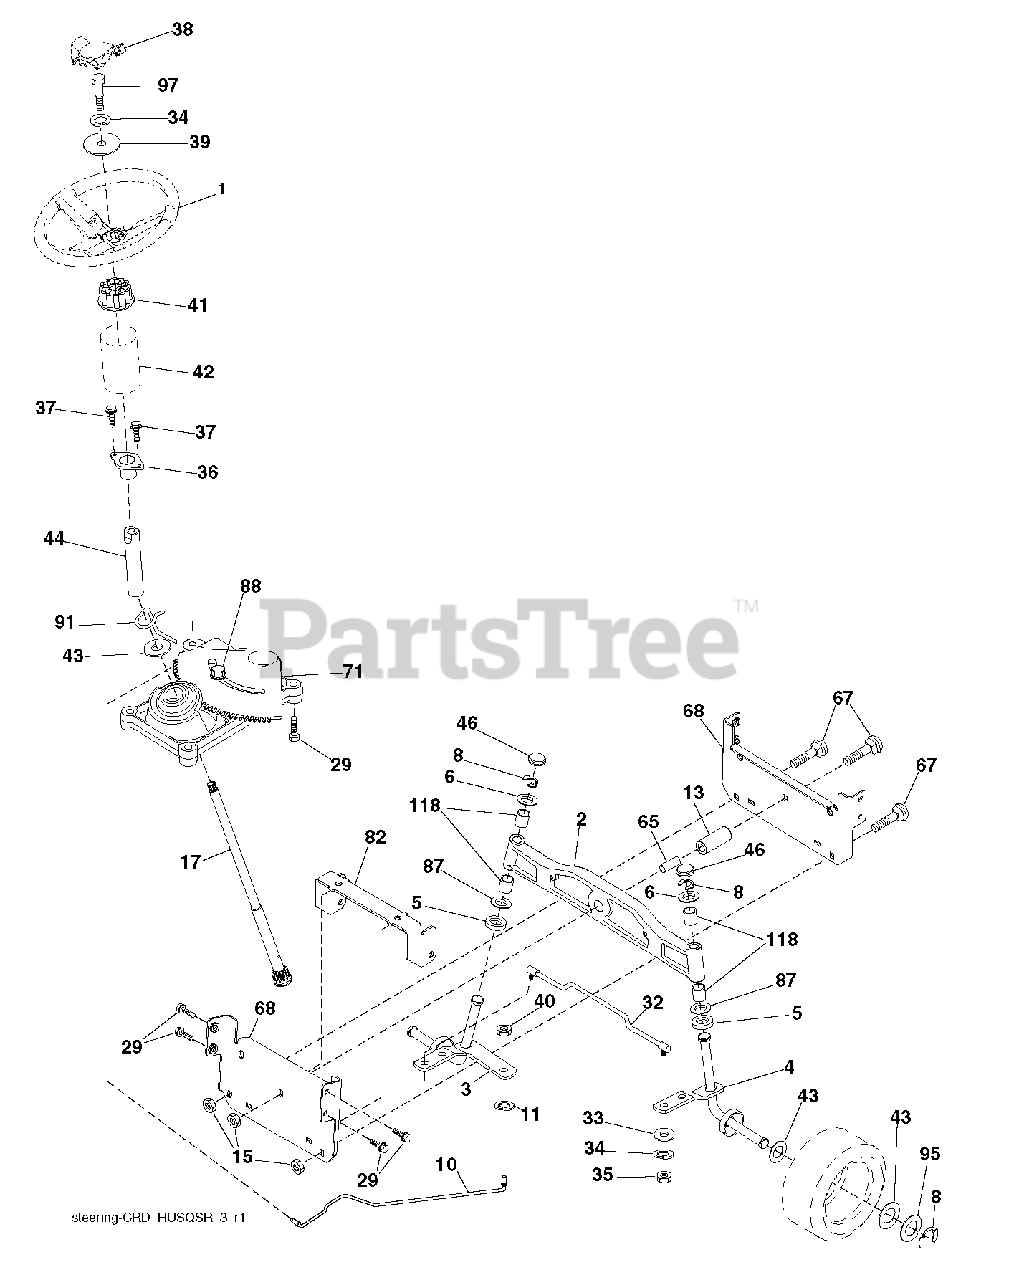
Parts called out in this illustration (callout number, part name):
1	WHEEL.STEER.HUSQ.SR.498.OVMLD
2	AXLE.ASM.LT.CAST.LGHTWGHT
3	SPINDLE.ASM.LH.15"TIRES
4	SPINDLE.ASM.RH.15"TIRES
5	THRUST WASHER
10	DRAGLINK.15".TIRES.2001
11	WASHER, LOCK 3/8
13	TUBE, PIVOT AXLE (2 2)
15	NUT LOCK FLG 3/8-16 UNC
17	SHAFT STEERING SPLINE
29	SCREW, 3/8-16X3/4
32	TIE ROD
33	WASHER M
34	LOCKWASHER
35	NUT, CROWNLOCK
36	BUSHING, STEERING
37	SCREW.TT.#10-32X.5.3/8.FLANGE
38	INSERT.CAP.WHL.STRG.HUSQ.PREM
39	WASHER.11/32
40	NUT CROWNLOCK 3/8-24
41	ADAPTER, WHEEL STNG..
42	STEERING.BOOT.HUSQ.LT
44	SHAFT.EXTEN.STRG.SPLINE
46	CAP.SPINDLE.BLACK
65	SPACER.BRACE.AXLE
67	BOLT CARRIAGE
68	BRACE.AXLE.15"TIRES
71	STEERING ASM
82	BRACKET.SUSP.CHASSIS.FRONT.15
87	WASHER, FLAT .781 X 1 1/2"
88	BOLT, SHOULDER 7/16-20
91	CLIP.STEERING
95	WASHER.HARDENED
97	BOLT 5/16-18 X 4 W/PATCH
118	BUSHING, AXLE CAST
